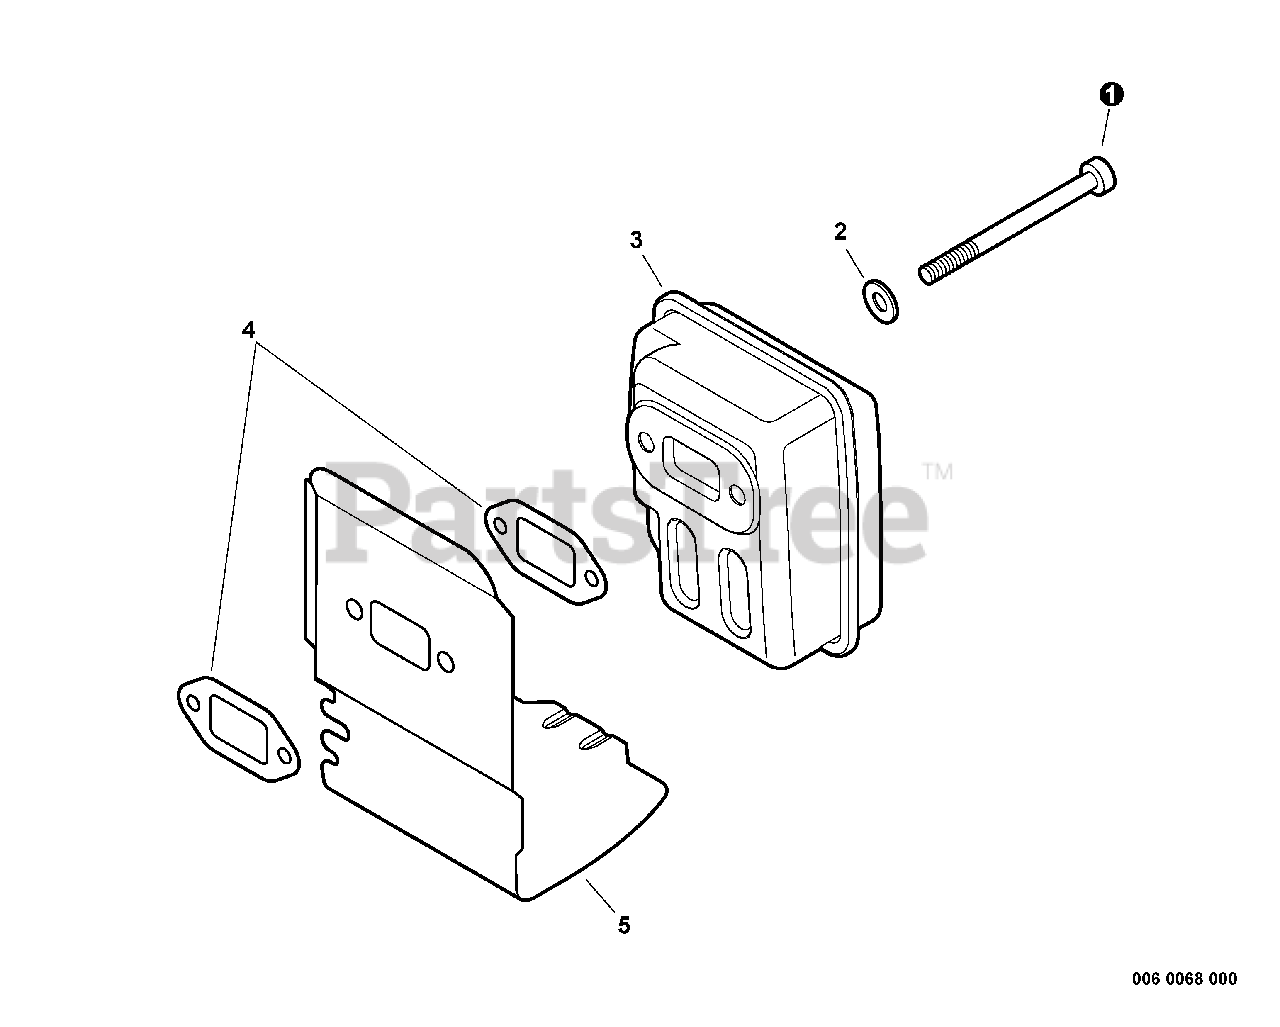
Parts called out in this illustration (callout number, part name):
1	SCREW - 5X55
2	WASHER - 5
3	MUFFLER
4	GASKET, EXHAUST
5	SHIELD, EXHAUST
